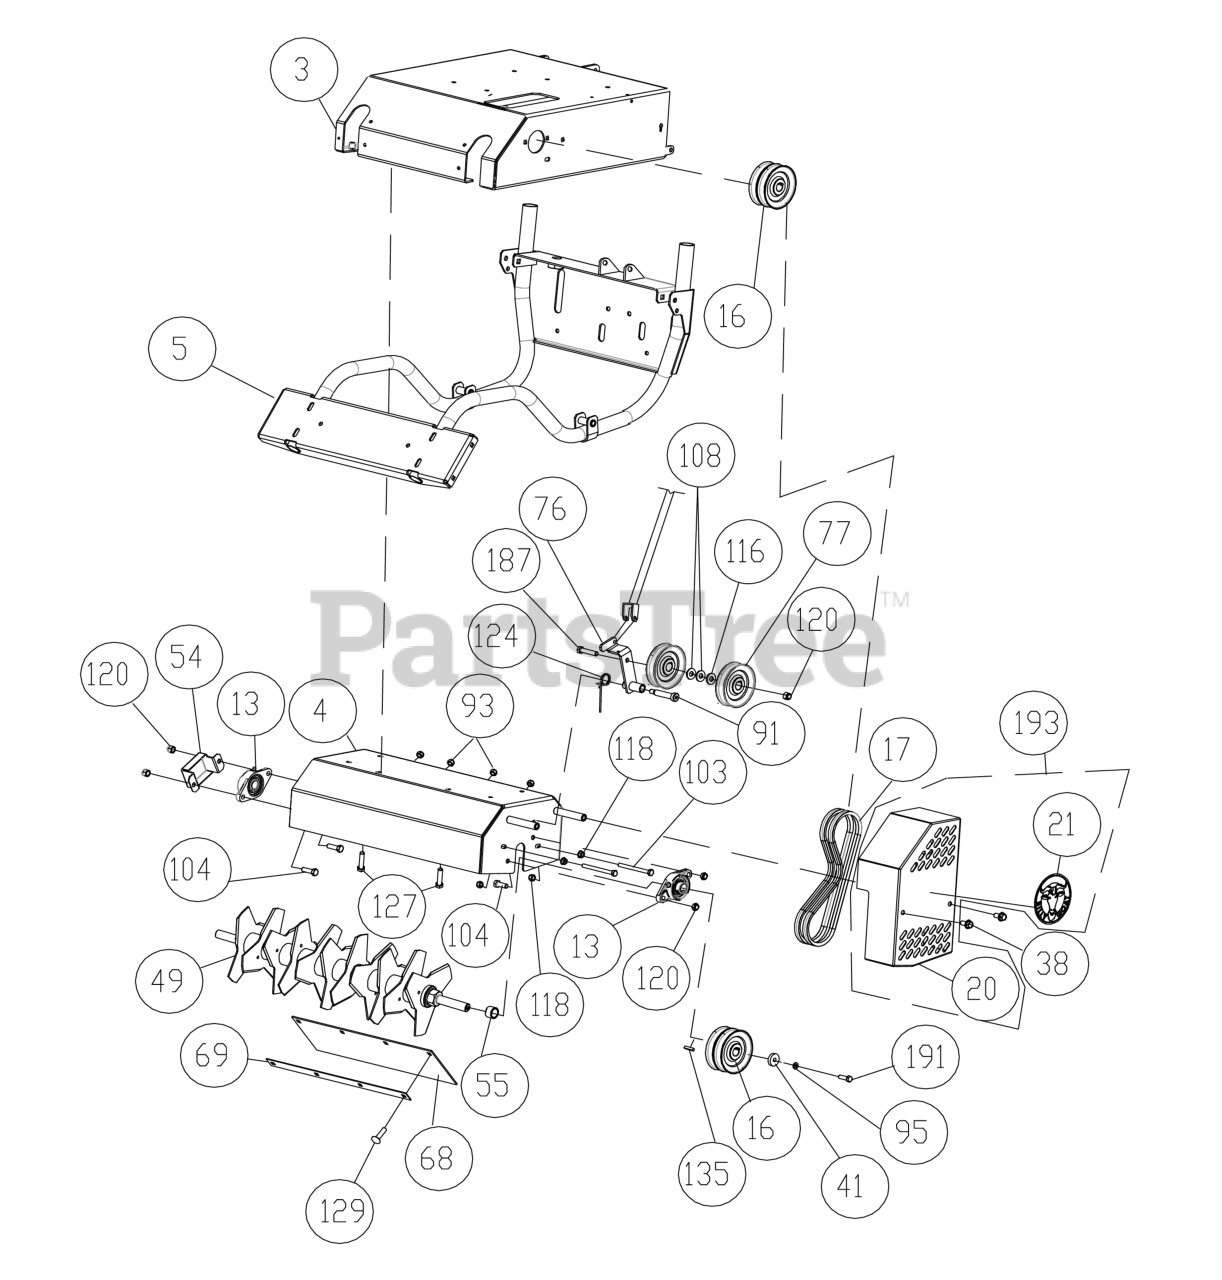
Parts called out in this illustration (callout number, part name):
3	ENGINE BASE WA
4	HOUSING VERTICUTTER WA
5	FRAME SUPPORT OS900SP WA
13	BEARING 3/4" CAST FLANGE W/ZERK
16	PULLEY 0.75" ID X 4" 4L SECTION
17	BELT 6381 POWER RATED
20	GUARD REEL BELT
21	LABEL DECAL SM CIRCLE
38	SER HEX WASHER 3/8" - 16
41	WASHER 1.125 OD X 0.344 ID X .25 THK ZP
49	REEL SUB ASSY OS901SPHD
54	GUARD BEARING REEL
55	SPACER SEED BOX AXLE
68	DEFLECTOR RUBBER OS900SP
69	BAR CLAMP DEFLECTOR
76	ARM IDLER WA REEL ENGAGE
77	PULLEY IDLER 2.75" OD X 3/8" BORE
91	BOLT SHOULDER 1/2" X 2"
93	NUT LOCK 5/16"-18 HEX Z/P
95	WASHER LOCK 5/16 ST MED
103	SCREWCAP 5/16"-18X3 1/2" HCS ZP
104	SCREWCAP 3/8"-16 X 1" HCS ZP
108	WASHER 5/16" FLATWASHER Z/P
116	WASHER 3/8"SAE 13/32"X13/16"X1/16"
118	NUT FLANGE 5/16"-18 ZP
120	NUT LOCK 3/8-16 LT WT THIN ZP
124	SPRING IDLER MULE DRIVE
127	SER HEX WASHER FLNG SCREW 5/16"-18 X 3/4"
129	BOLT CARRIAGE 5/16"-18 X 3/4" ZP
135	KEY 3/16" SQ X 1 1/4"
147	PIN CLEVIS 1/4" X .75"
150	PIN CLIP HITCH 0.051 X 3/4"
187	SCREWCAP 3/8"-16X2 1/2" HCS ZP
191	SCREWCAP 5/16"-24 X 1" GR.8 ZP W/PATCH
193	GUARD REEL BELT W/LABELS
